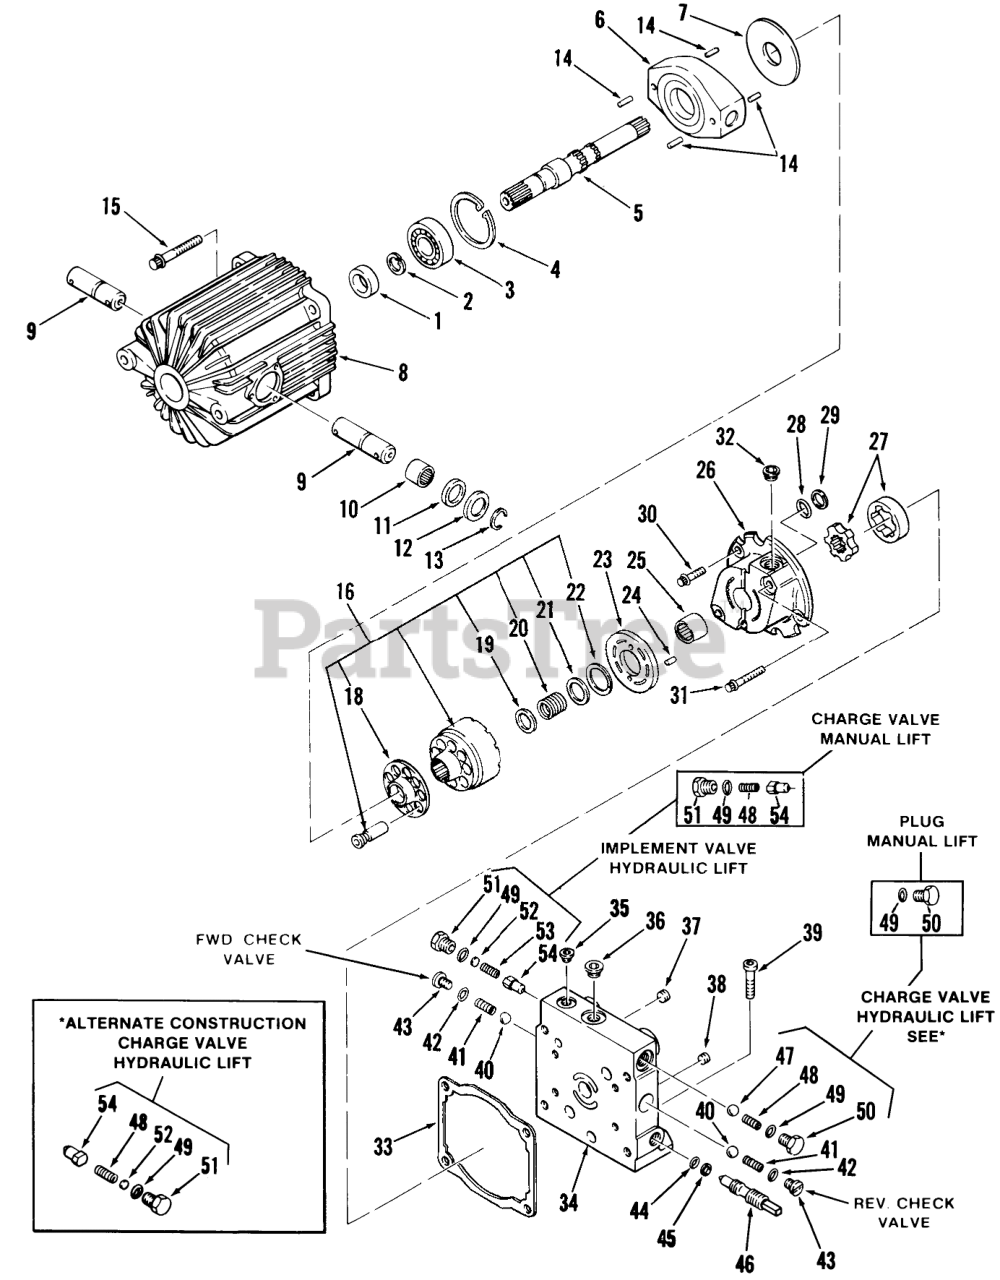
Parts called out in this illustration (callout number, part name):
1	SEAL
2	Snap Ring
3	Ball Bearing
5	Pump Shaft
6	Variable Swash Plate
7	Thrust Plate
8	Pump Housing
9	Trunnion Shaft
10	Needle Bearing
11	SEAL
12	WASHER-LAMBERT
13	RING-LAMBERT
14	Spirol Pin
15	Cap Screw
16	Cylinder Block Kit Inc 18-22
18	RETAINER-SUN 3100194
19	Spacer
20	Spring
21	Front Washer
22	RING-SUN9006250-0112
23	PLATE-VALVE
24	Locating Pin
25	Needle Bearing
26	Charge Pump Housing
27	Assy-Gerotor
28	O RING
29	RING BACKUP
30	Cap Screw Short
31	Cap Screw Long
32	Socket Head Plug
33	Gasket-Pump
34	End Cap-Pump
35	Socket Head Plug
36	Socket Head Plug
37	Pipe Plug
38	Pipe Plug
39	Cap Screw
40	Ball
41	Spring
42	O RING
43	PLUG
44	O-RING
45	Back Up Ring
46	VALVE
47	Ball
48	Spring Chg. Rel. Valve
49	O RING
50	Plug
52	Shim Set
53	Spring-Implement Valve
54	Cone
